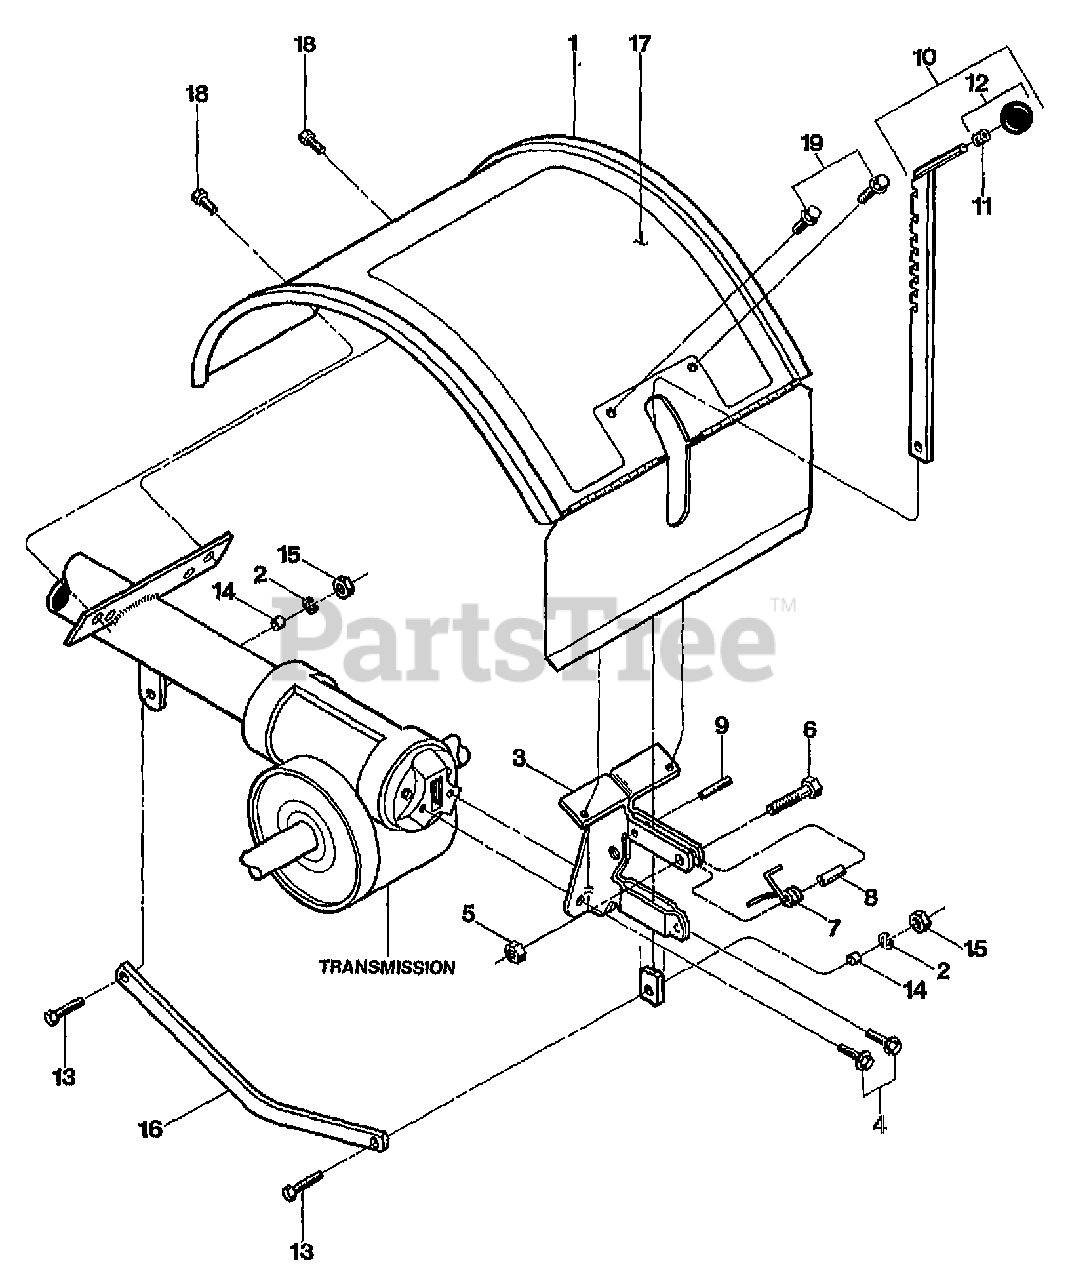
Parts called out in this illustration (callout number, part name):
1	HOOD W/DECALS JR (INCL. 17)
2	WASHER-LK .375
3	BRKT W/ROLL PIN (9308)(INCL. 9)
4	SCR-HFLK 5/16-18X.75
5	NUT-LK 1/4-20
6	SCR-HH 1/4-20X1.0
7	SPRING-TORSION
8	SPACER-.250X.343X.375
9	PIN-ROLL .25 X 1 (SPIRAL)
10	DEPTH REGULATOR W/KNOB (INCL. 11 & 12)
11	RING-TOLERANCE .5325 ID
12	KNOB-CONTROL (INCL. 11)
13	SCR-HH 3/8-16X1.25
14	BUSHING-.5X.375X.3
15	NUT-HEX 3/8-16
16	DRAG BAR-BENT
17	DECAL-HOOD JR
18	SCR-HWH 5/16-18 X .5 STH
19	SCR-HWH 1/4-20 X .5 STH (ATTACHES HOOD TO DEPTH REGULATOR BRACKET)
